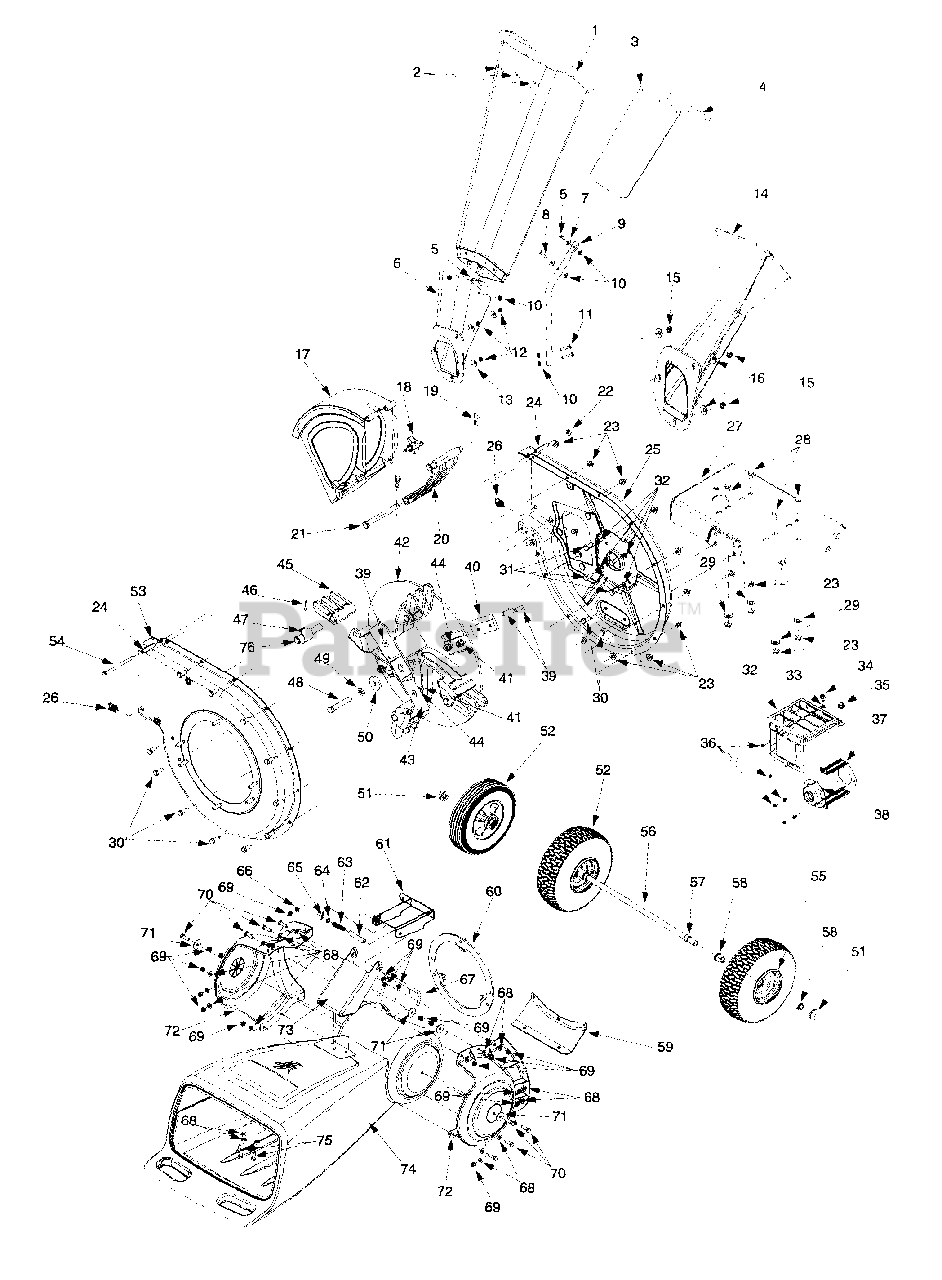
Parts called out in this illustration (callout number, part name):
1	Chipper Chute
2	Pop Rivet
3	Chute Flap
4	Flat Strip
5	Hex Cap Screw 1/4-20 x .620
8	Hex Cap Screw 1/4-20 x 1.25
10	Hex Flange Nut 1/4-20
11	Hex Cap Screw 1/4-20 x 1.25
12	Hex Nut 5/16-18
13	Bell Washer .340 ID x .872 OD
15	Hex Nut 5/16-18
16	Bell Washer .340 ID x .872 OD
18	Knob 5/16-18
19	Cotter Pin
21	Clevis Pin
22	Hex Lock Nut 1/4-20
23	Flange Hex Lock Nut 5/16-18
24	Spacer
26	U Nut 5/16-18
28	Hex Cap Screw 5/16-18 x 1.5
29	Bell Washer 5/16 x 1.0
30	Hex Cap Screw 5/16-18 x .75
31	Hex Cap Screw 5/16-24 x .75
32	Lock Washer 5/16
33	Lock Washer 1/4
34	Hex Washer Screw 1/4-20 x .5
35	Hex Lock Nut 5/16-18
36	Hex Washer Screw
37	Muffler Bracket Guard
38	Deflector
39	Flat Screw 5/16-24 x 1.0
40	Chipper Blade
41	Hex Lock Nut 5/16-24
42	Impeller Asm
43	Shredder Blade
44	Lock Washer 5/16
45	Flail Blade
46	Spiral Pin
47	Spring Pin
48	Hex Cap Screw 3/8-24 x 2.25
49	Lock Washer 3/8
50	Flat Washer 3/8 x 1.25
51	Push Cap
52	Wheel Assy Comp 10.0 x 2.5
54	Hex Cap Screw 1/4-20 x 3.75
57	Spacer
58	Flange Bearing
62	Spacer
63	Compression Spring
64	Flat Washer 3/8 x .620 x .033
65	Cotter Pin
66	Flat Washer
67	Hex Lock Nut 5/16-18
68	Flat Washer .330 ID x .630 OD
69	Hex Lock Nut 5/16-16
70	Hex Cap Screw 5/16-18 x 1.0
71	Flat Washer .320 ID x 1.25 OD
72	Collar-Hopper
74	Hopper
75	Hex Cap Screw 5/16-18 x .75
76	Clevis Pin
